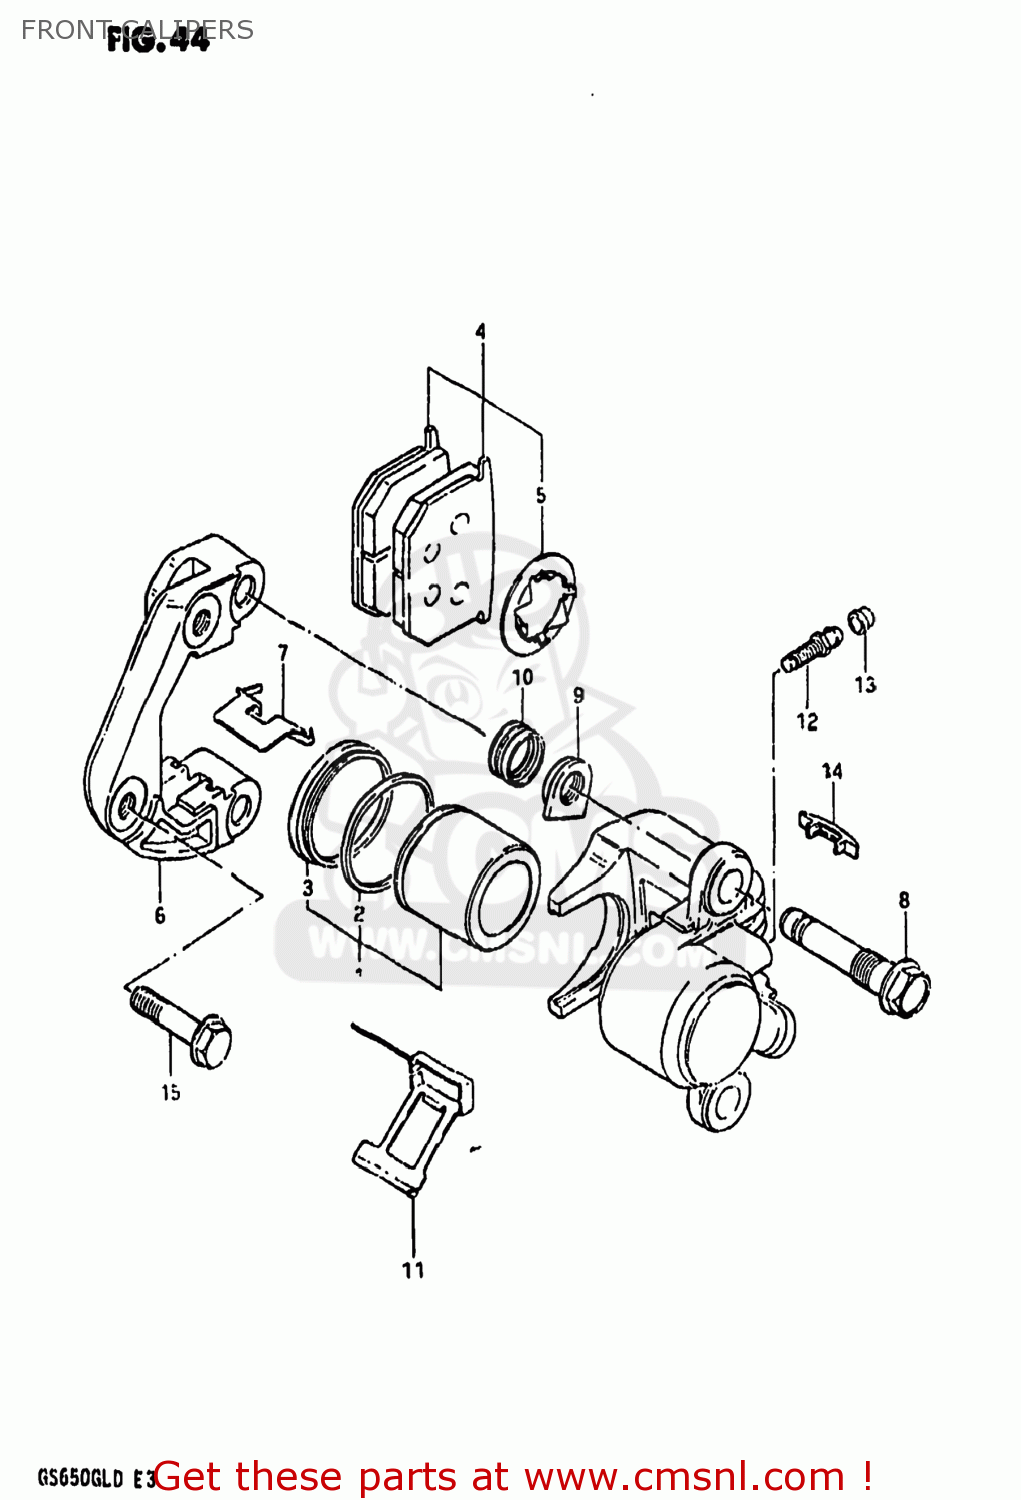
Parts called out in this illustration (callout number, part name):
1	PISTON SET
2	SEAL,PISTON
3	BOOT,PISTON
4	PAD & SHIM SET (MCA)
5	SHIM,PAD
6	HOLDER,CALIPER,LEFT
7	PAD,GUIDE
8	AXLE,CALIPER
9	NUT,CALIPER AXLE
10	BOOT
11	SPRING
12	BREATHER
13	CAP,BLEEDER PL
14	COVER,INDICATOR
15	BOLT
